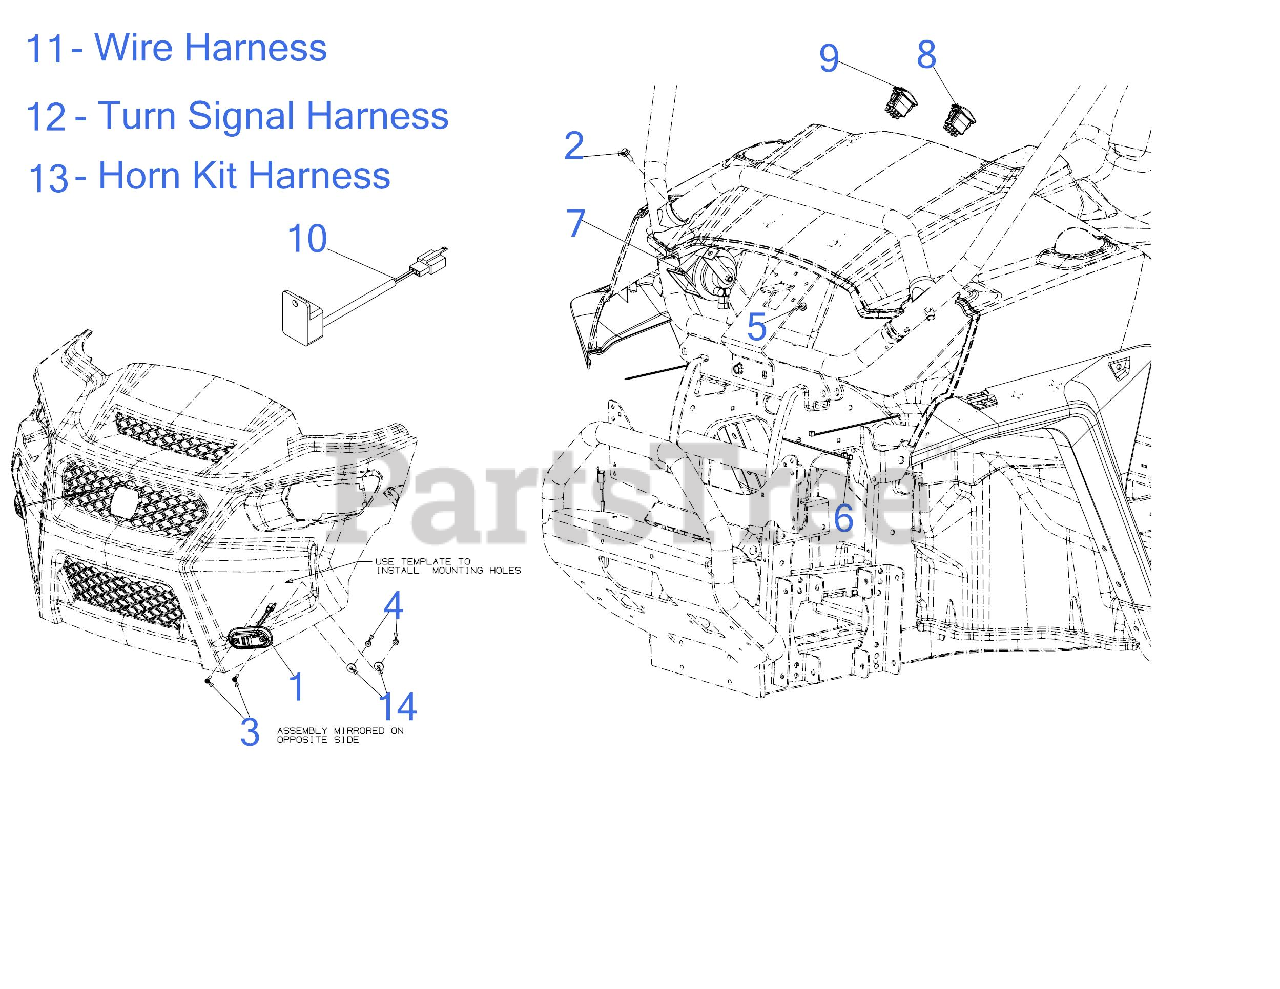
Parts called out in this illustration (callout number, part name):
1	TURN SIGNAL LIGHT ASSEMBLY
1	MOLEX CONNECTOR
2	SCREW 1/4-20 x .75 GR5
3	SCREW #8-32 x .750
5	FLANGE LOCK NUT
6	7" CABLE TIE
8	TURN INDICATOR SWITCH
9	HORN SWITCH
10	LED FLASHER
11	WIRE HARNESS
12	LED TURN SIGNAL HARNESS
13	HORN WIRE HARNESS KIT
14	FLAT WASHER .194x.620x.063
